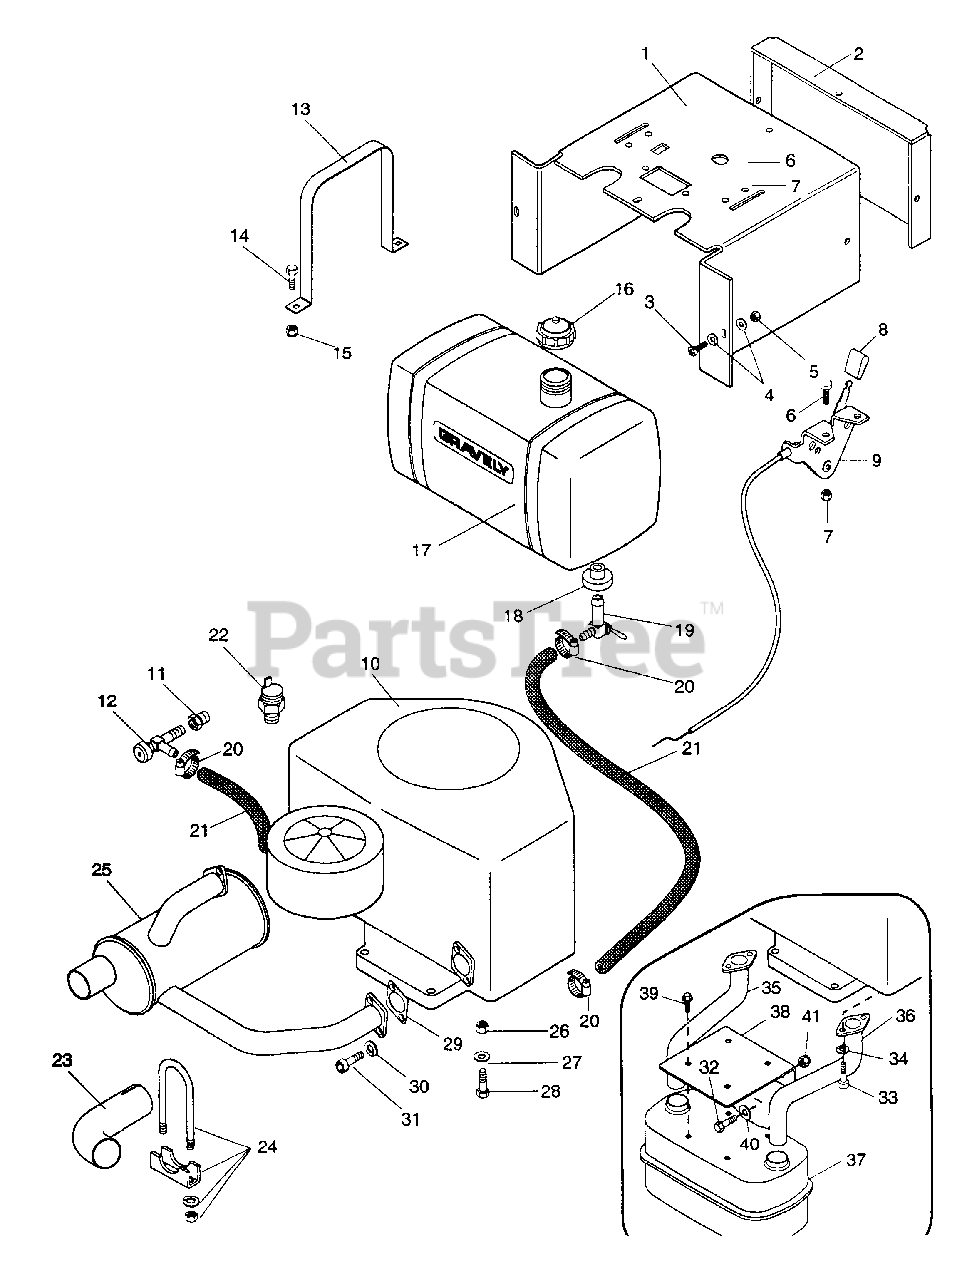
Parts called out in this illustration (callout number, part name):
1	Panel, Silkscreen
2	Cover, Instrument Panel
3	Screw, Machine .25-20 Pan Head
4	Washer, Flat Steel .281 x .62 x .065
5	Nut, Lock Nylon .250-20
6	Screw, Machine 10-32 x .50
7	Nut, Lock 10-32 Nylon
8	Knob
9	Assembly, Choke Control
9	Assembly, Throttle Control
10	Engine, 18 HP. Magnum, PS-58550 (02, 04)
10	Engine, 16 HP. B&S (01,03)
11	Adapter, Oil Drain
12	Cock, Oil Drain
13	Strap, Fuel Tank
14	Bolt, Hex .25-20 x .63
15	Nut, Lock Nylon .250-20
16	Cap, Fuel Tank
17	Tank, Fuel
18	Bushing
19	Valve, Ball Shut off
20	Hose Clamp
21	Gas Line, Bulk
22	Switch, Pressure
23	Deflector, Exhaust (02, 04)
24	Clamp U 1.75 (02,04)
25	Muffler (02,04)
26	Nut, Lock Nylon .312-18
27	Washer, Flat Steel .344 x .66 x .065
28	Bolt, Hex .31-18 x 1.50 Gr. 5
29	Gasket, Exhaust (02,04)
30	Washer, Lock .313 x .078
31	Screw, Cap .31-18 x .75
32	Bolt-Hex .38-16 x 1.50 Gr. 5
33	Screw, Socket head M8 x 1.25 x 20mm
34	Washer, Lock .313 x .078
35	Headpipe, Nelson Q-33477, 16 HP B&S
36	Headpipe, Nelson Q-33476, 16 HP B&S
37	Muffler, Nelson # 24392-N
38	Bracket, Muffler, B&S
39	Screw, Tapping 12-24 x .75
40	Washer, Flat Steel .438 x 1.0 x .083
41	Nut, Lock Nylon .375-16
